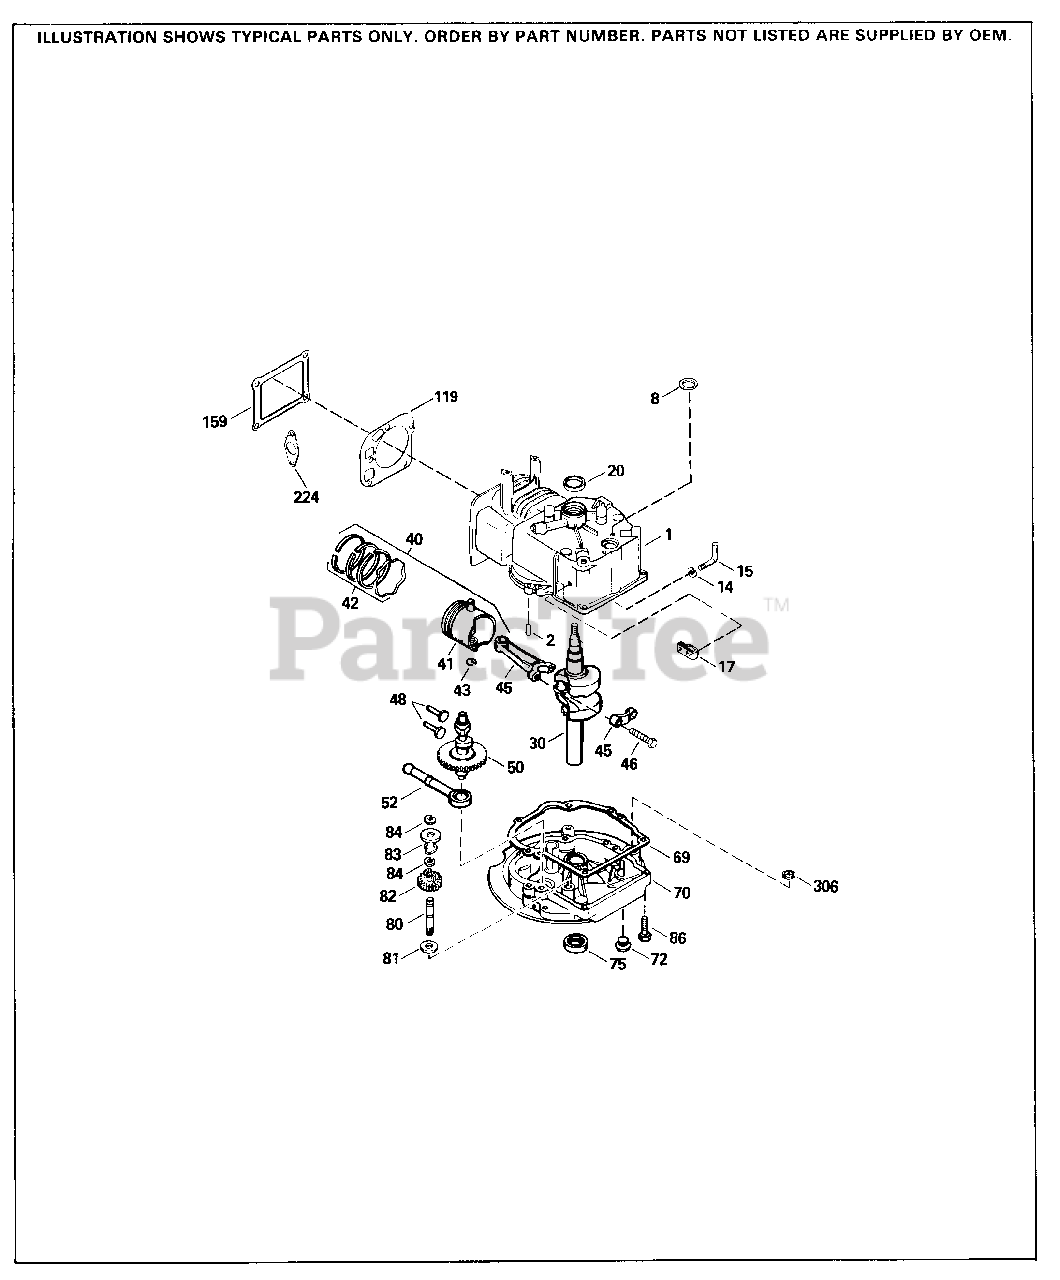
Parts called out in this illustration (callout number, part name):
1	"Cylinder (Incl. 2 & 20) (2-5/8" Bore)
2	Dowel Pin
8	Breather Gasket
14	Flat Washer
15	Governor Rod (Incl. 14)
17	Governor Lever Clamp
20	Oil Seal
30	Crankshaft
40	Piston, Pin & Ring Set (.020" OS) (In cl. 41, 42 & 43)
40	Piston, Pin & Ring Set (Std.) 2-5/8"B ore
40	Piston, Pin & Ring Set (.010" OS)
41	Piston & Pin Assembly (Std.) (Incl. 4 3)2-5/8")
41	Piston & Pin Assembly (.010" OS) (Inc l. 43)
41	Piston & Pin Assembly (.020" OS) (Inc l. 43)
42	Ring Set (Std.) (2-5/8" Bore)
42	Ring Set (.010" OS)
42	Ring Set (.020" OS)
43	Piston Pin Retaining Ring
45	Connecting Rod (Incl. 46)
46	Connecting Rod Bolt
48	Valve Lifter
50	Camshaft (MCR)
52	Oil Pump Ass'y.
69	Mounting Flange Gasket
70	Mounting Flange (Incl. 72, 75 & 80)
72	Oil Drain Plug
75	Oil Seal
80	Governor Shaft
81	Flat Washer
82	Governor Gear (Incl. 81)
83	Governor Spool
84	Retaining Ring
86	Screw, 1/4-20 x 1-1/4"
119	Cylinder Head Gasket
159	Rocker Arm Cover Gasket
224	Intake Gasket
306	Fill Tube Gasket
